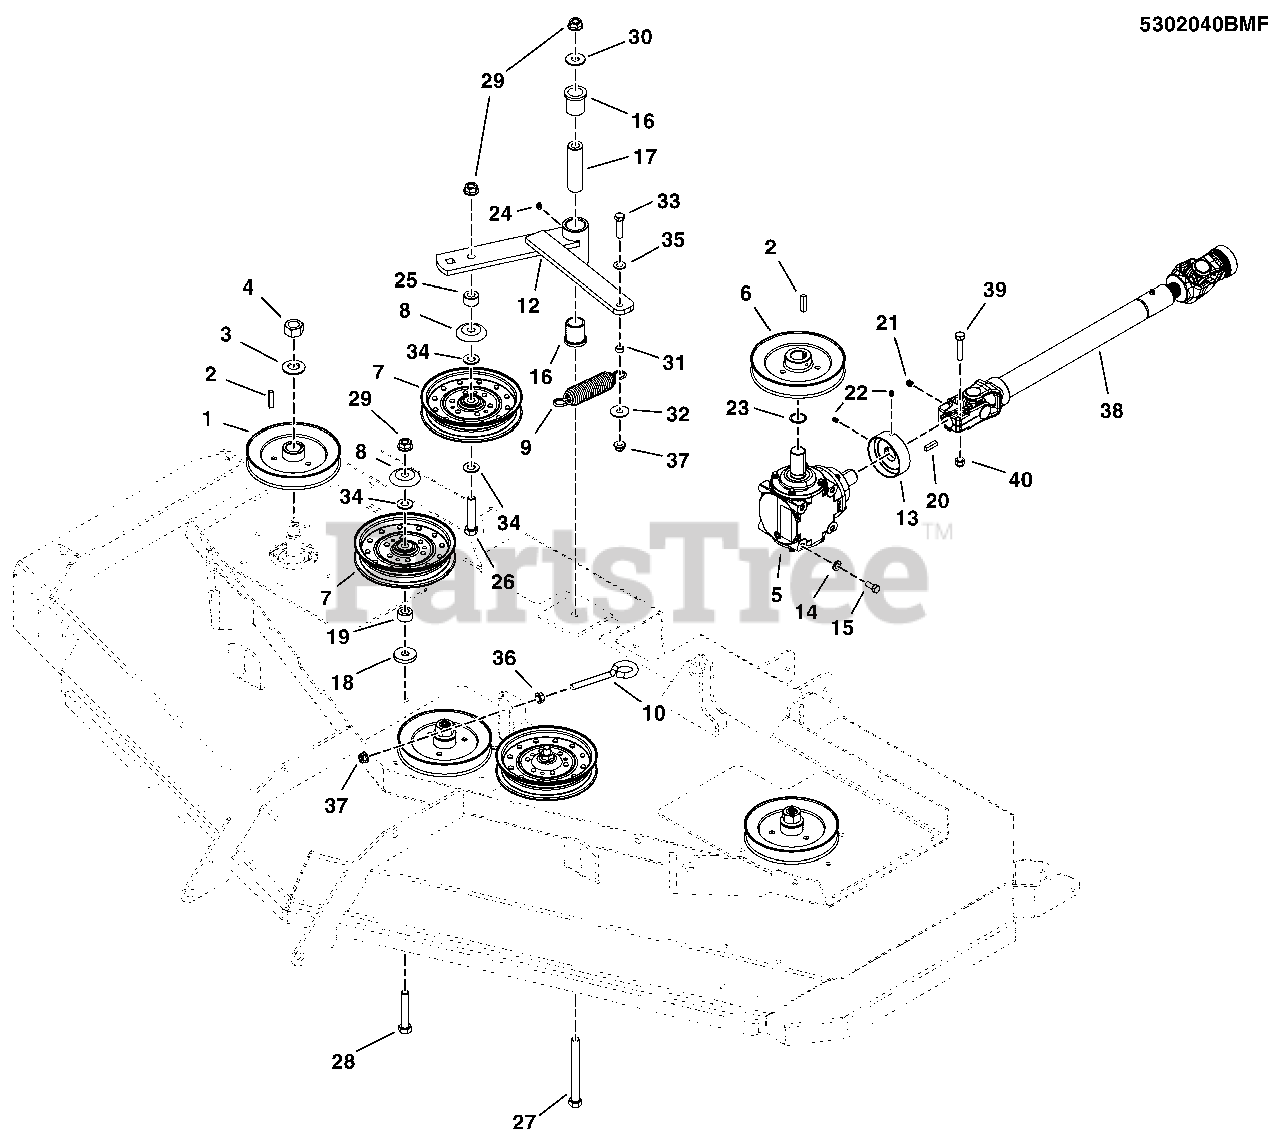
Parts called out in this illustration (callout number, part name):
1	PULLEY, Spindle, Black (52" Deck, S/N: 586 & above)
2	KEY, 1/4 SQ. X 1-1/4
3	WASHER, 3/4" Belleville (Included with Complete Spindle Assembly)
4	NUT, 3/4-16 Hex (Included with Complete Spindle Assembly)
5	GEAR BOX, RIGHT ANGLE
6	PULLEY, 6.25" SPLIT STEEL W/ 1" ID
7	*PULLEY, FLAT IDLER, 6-3/4"
8	SHIELD, PULLEY BEARING, CZ
9	SPRING-EXT, 1.25 ODX5.70LGX.142WR, BLK
10	EYEBOLT, 3/8-16 X 5, 2.88 THRD (5021812)
12	WELD., IDLER ARM, S800X-72 - RED
13	GUARD, TRASH, S800X
14	WASHER, Flat
15	CAPSCREW, Hex Head, 5/16-18 x 3/4
16	BUSHING, FLANGE
17	SPACER, .52 X 1.00 X 3.50
18	WASHER, .53 X 1.50 X .25
19	SPACER, .52 X 1.00 X .56, PM, CZ
20	KEY, 1/4 Square x 1
21	SET SCREW, 3/8-16 X 3/8
22	SOC SET SCREW, 1/4-20X3/8, DRI-LOC PATCH
23	SNAP RING, EXTERNAL, 1 SHAFT
24	GREASE FITTING, 1/4-28 STRAIGHT
25	SPACER, .52 X 1.00 X .63, CZ
26	BOLT, 1/2-13 X 2-1/2 GD5 YZ
27	BOLT, 1/2-13 X 5" GD5 YZ
28	BOLT, 1/2-13 X 2-3/4 GD5 YZ
29	NUT, Hex Flange, 1/2-13
30	WASHER, 1/2" USS
31	SPACER, .38 X .50 X .27, CZ
32	WASHER, Fender, 3/8
33	CAPSCREW, Hex Head, 3/8-16 X 1-1/2
34	WASHER, 1/2
35	WASHER, Flat, 3/8
36	NUT, Hex, Serrated Flange, 3/8-16 (S/N 616 & up)
37	NUT, 3/8-16, Hex Flange Nylock
38	SHAFT, TELESCOPING DRIVE, OUT-FRONT
38	DRIVE SHAFT SEALED S800 GAS - NET
39	CAPSCREW, Hex Head, 3/8-16 X 1-3/4
40	NUT, Hex, Nylon Lock, 3/8-16
